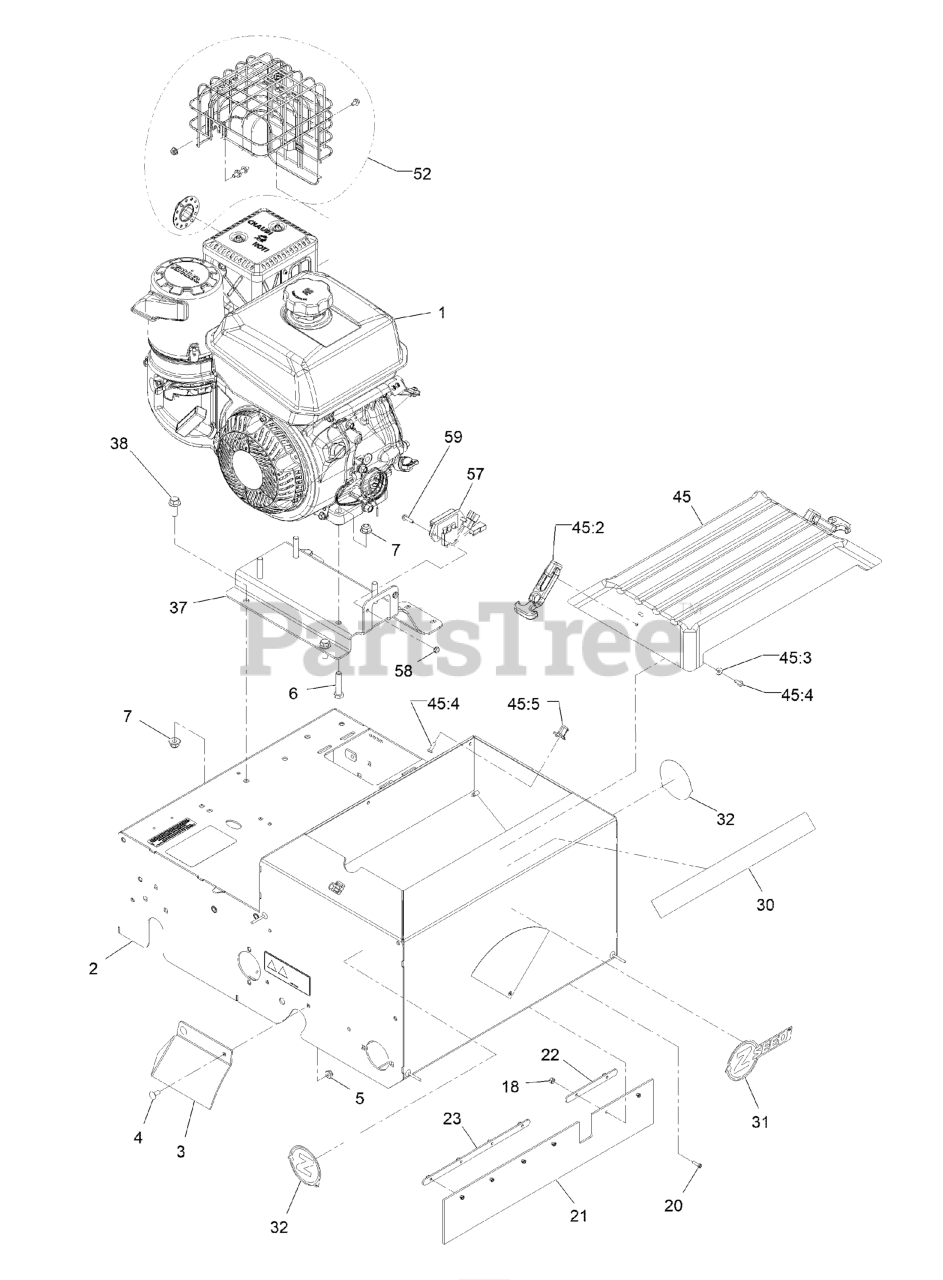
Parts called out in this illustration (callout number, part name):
2	Frame-Service ASM
4	SCREW-CARR
6	SCREW-HH
7	NUT-HF, NI
18	NUT-LOCK
20	SCREW-SHH
21	GUARD-DUST
22	PLATE-RETAINER
23	PLATE-RETAINER
30	Decal-Slicer Seeder Logo
31	DECAL-Z-SEED LOGO
32	Decal-Z-Logo
37	Plate-Engine
38	SCREW-HHF 3/8-16 X 1
45	SEEDER COVER KIT
45:2	LATCH-RUBBER
45:3	WASHER-FLAT
45:4	SCREW-PPH
45:5	LATCH-KEEPER
52	KIT-CH395 MUFFLER GUARD
57	Regulator
58	KEPS Nut
59	SCREW-HWH
